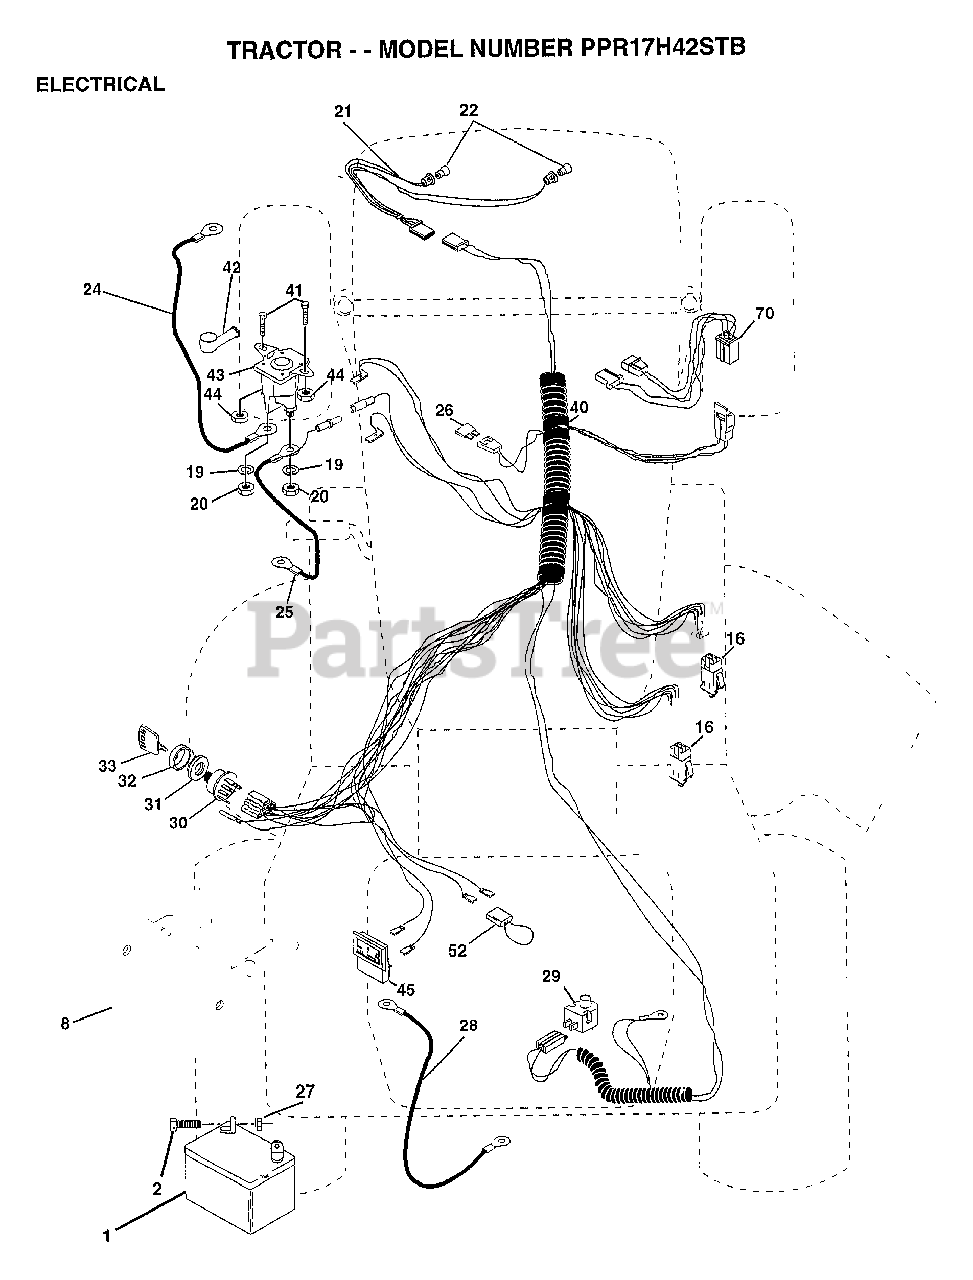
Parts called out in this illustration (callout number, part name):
2	BOLT LT
8	"CASE,BATTERY.MECH"
16	SWITCH INTERLOCK
20	NUT
21	HARNESS.ASM.LIGHT W/4152J
22	HEADLAMP BULB
24	"CABLE T, BATTERY"
25	CABLE.BTRY.6GA.RD
26	FUSE.15 AMP
27	NUT
28	CABLE T
29	SWITCH SEAT
30	SWITCH IGN 4POS
31	NUT IGNITION
32	COVER KEY SWITCH
33	KEY
40	HARNESS.IGNITION
41	BOLT HXHD FIN
44	NUT HXKEP 1/4X20
52	PROTECTION LOOP
70	HARNESS.ENGINE.B&S
